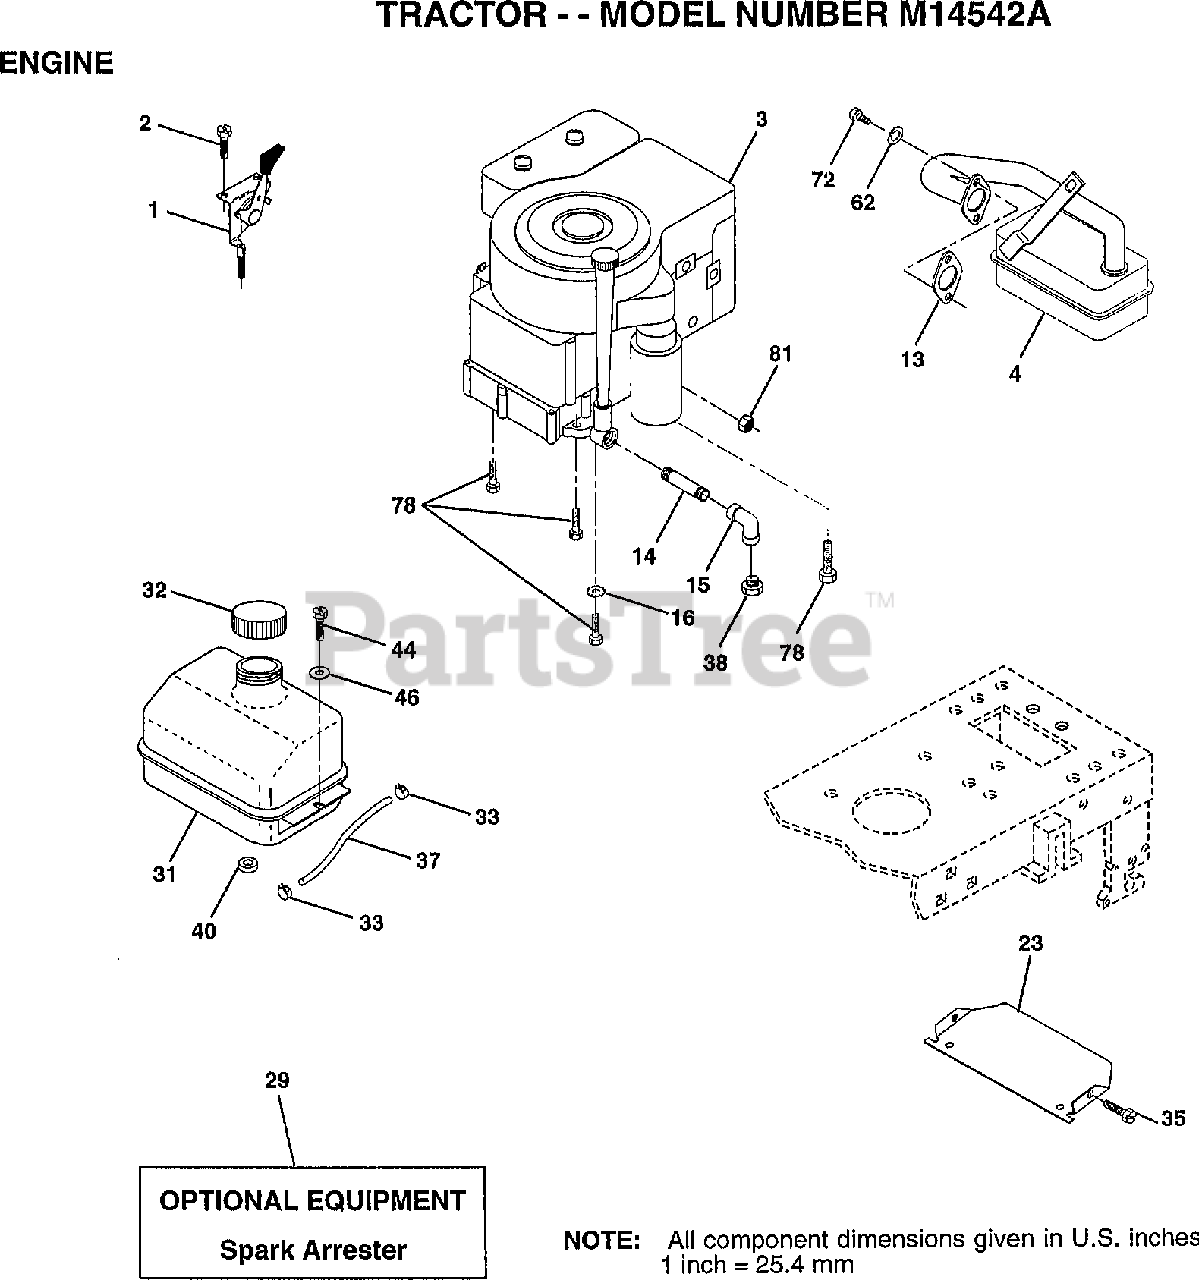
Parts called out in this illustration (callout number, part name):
1	CONTROL THROTTLE
2	SCREW LT
4	MUFFLER
13	GASKET ENG 1 313 LD TIN PLATED
14	PIPE NIPPLE
15	ELBOW
16	LOCKWASHER
23	SHIELD-HEAT
31	TANK.FUEL.LT.
32	CAP ASM FUEL
33	HOSE CLAMP
35	SCREW
37	LINE FUEL
44	SCREW HEX CRT
46	WASHER
62	LOCKWASHER
72	SCREW
78	SCREW
81	NUT
